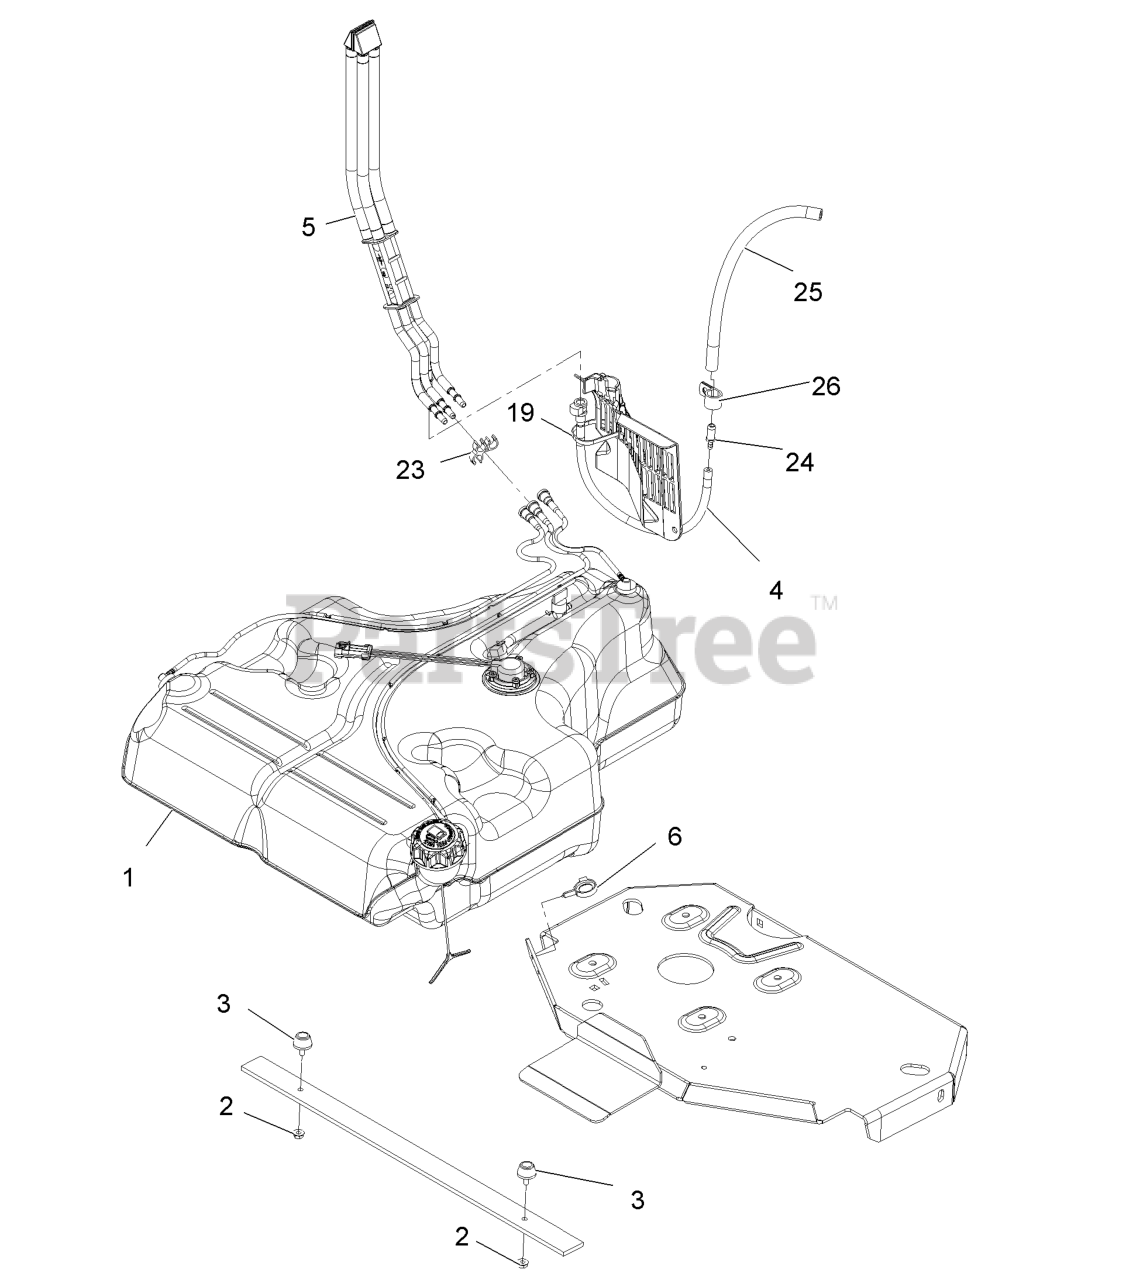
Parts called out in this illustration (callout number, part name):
3	BUMPER-RUBBER
4	HOSE ASM
5	FUEL MANIFOLD VENT ASM
6	CLAMP-HOSE
19	TIE-PLASTIC
23	CLIP-SPACER
24	FITTING-STRAIGHT
25	HOSE-FUEL
26	CLIP-LOOM
